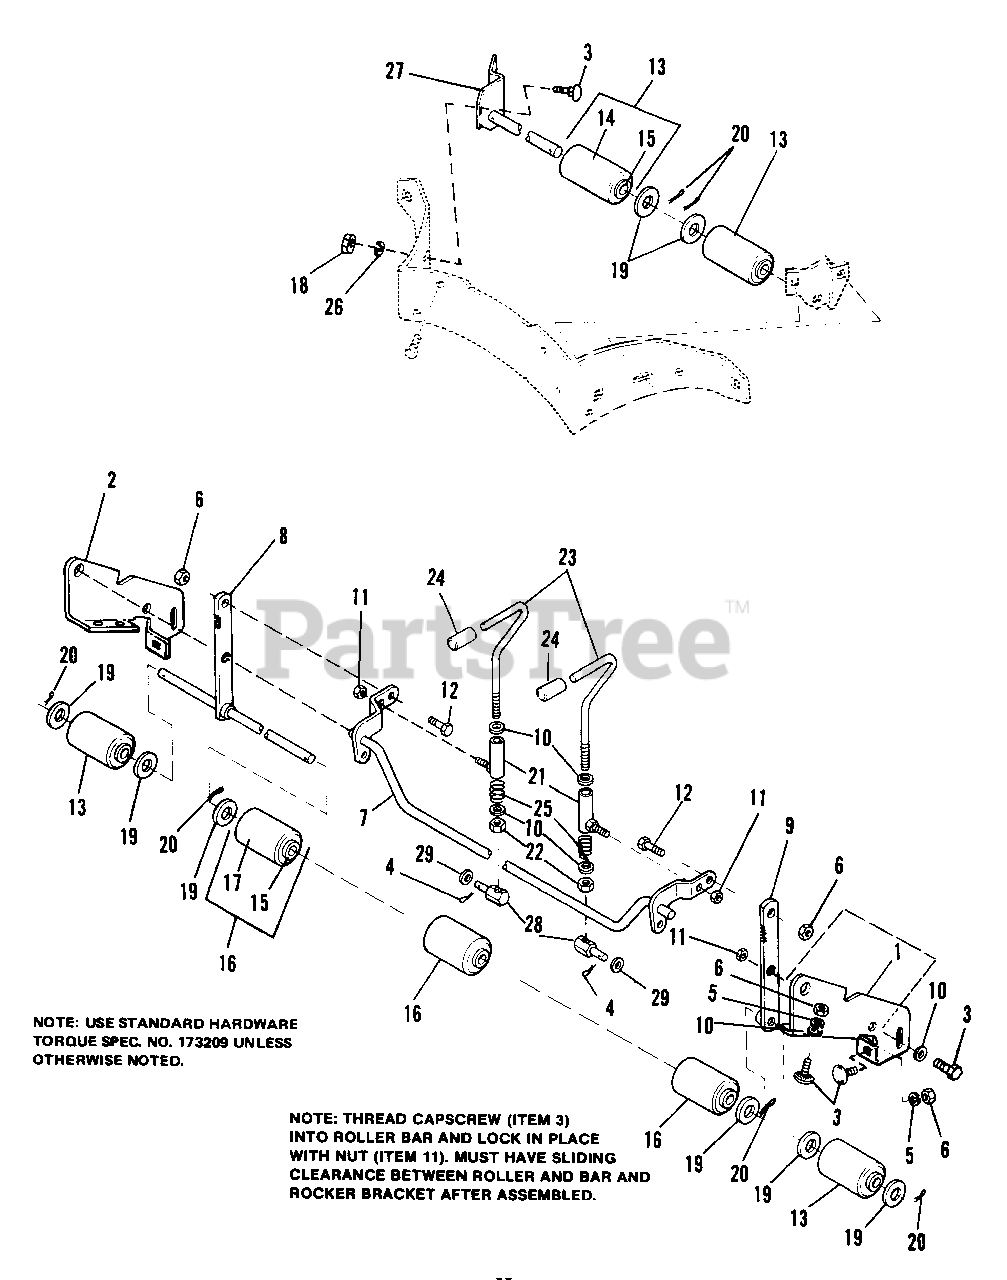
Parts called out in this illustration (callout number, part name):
1	BRACKET, Roller, L.H.
2	BRAKCET, Roller, R.H.
3	CARRIAGE BOLT, 3/8-16 x 3/4
4	PIN. Cotter. 3/32 x 5/8
5	LOCKWASHER, 3/8
6	NUT, Hex Full, 3/8-16
7	ROCKER ARM ASSY
8	SHAFT ASSY, Roller
9	BAR ASSY, Roller
10	WASHER, Plain, 3/8
11	NUT, Hex Full Lock, 3/8-16
12	CAPSCREW, Hex Hd., 3/8-16 x 1
13	ROLLER ASSY
14	ROLLER
16	ROLLER ASSY
17	ROLLER
18	NUT, Hex Full, 5/16-18
19	WASHER, Plain, 5/8
20	PIN, Cotter, 3/16 x 1
21	SOCKET ASSY
22	NUT, Hex Jam, 3/8-16
23	HANDLE, Adjusting
24	GRIP
26	LOCKWASHER. 5/16
27	BRACKET & SHAFT ASSY
29	WASHER, Plain, 5/16
